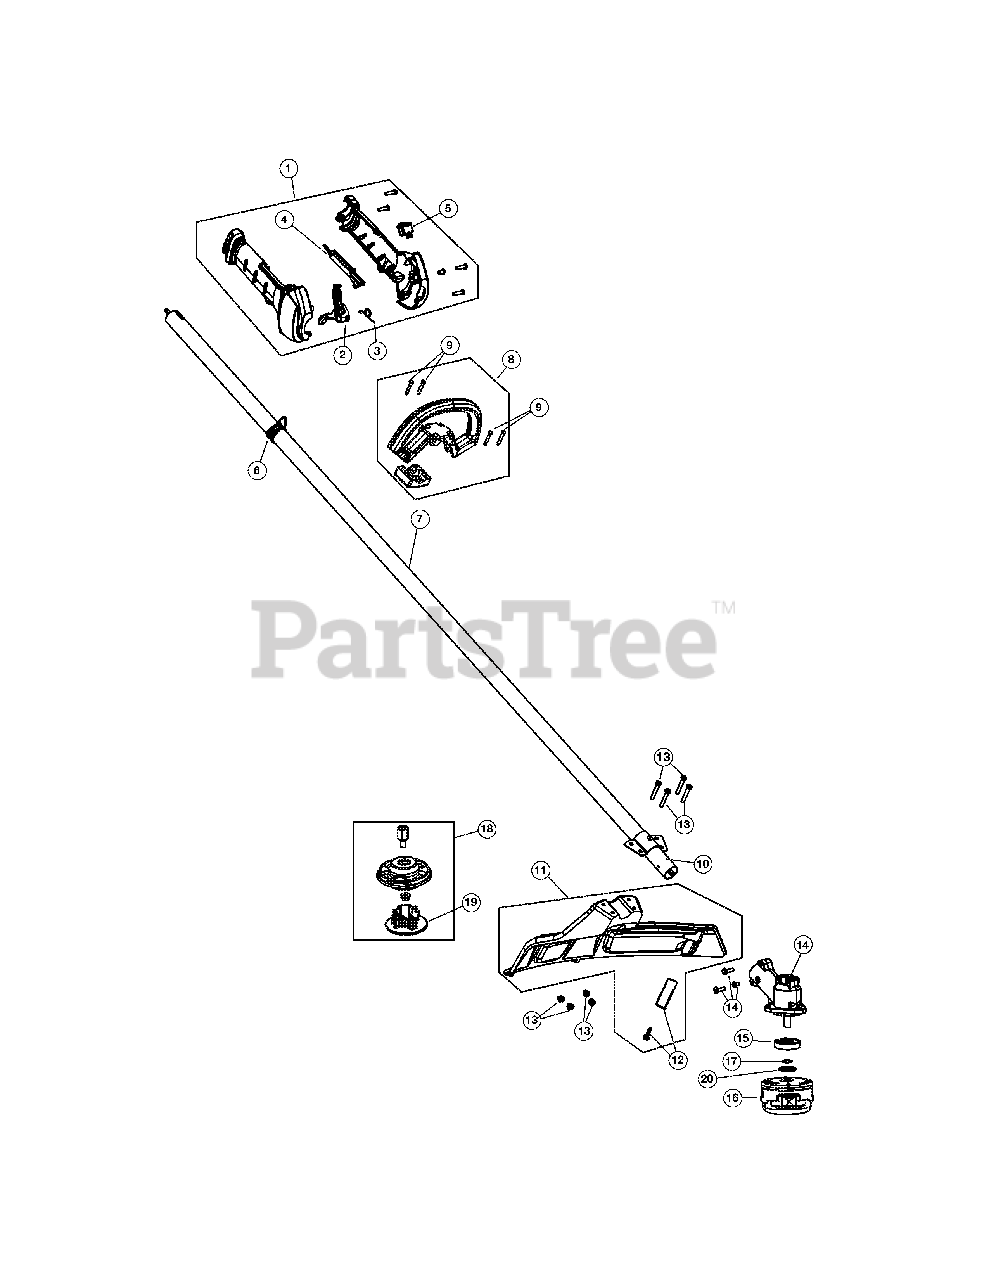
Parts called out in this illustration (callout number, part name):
1	Throttle Housing Assembly (includes 2-5)
2	Throttle Trigger
3	Spring
4	Throttle Lock-Out
6	Shoulder Strap Clip
7	Driver Shaft Housing
8	D-Handle Assembly (includes 9)
10	Flexible Drive Shaft
11	Shield Assembly (includes 12)
12	Blade Assembly
13	Screw & Nut
14	Gearbox
15	Gearbox Spacer
16	Cutting Head Assembly
17	Palnut
18	Fixed Line Head
19	Glide Plate
20	Washer
